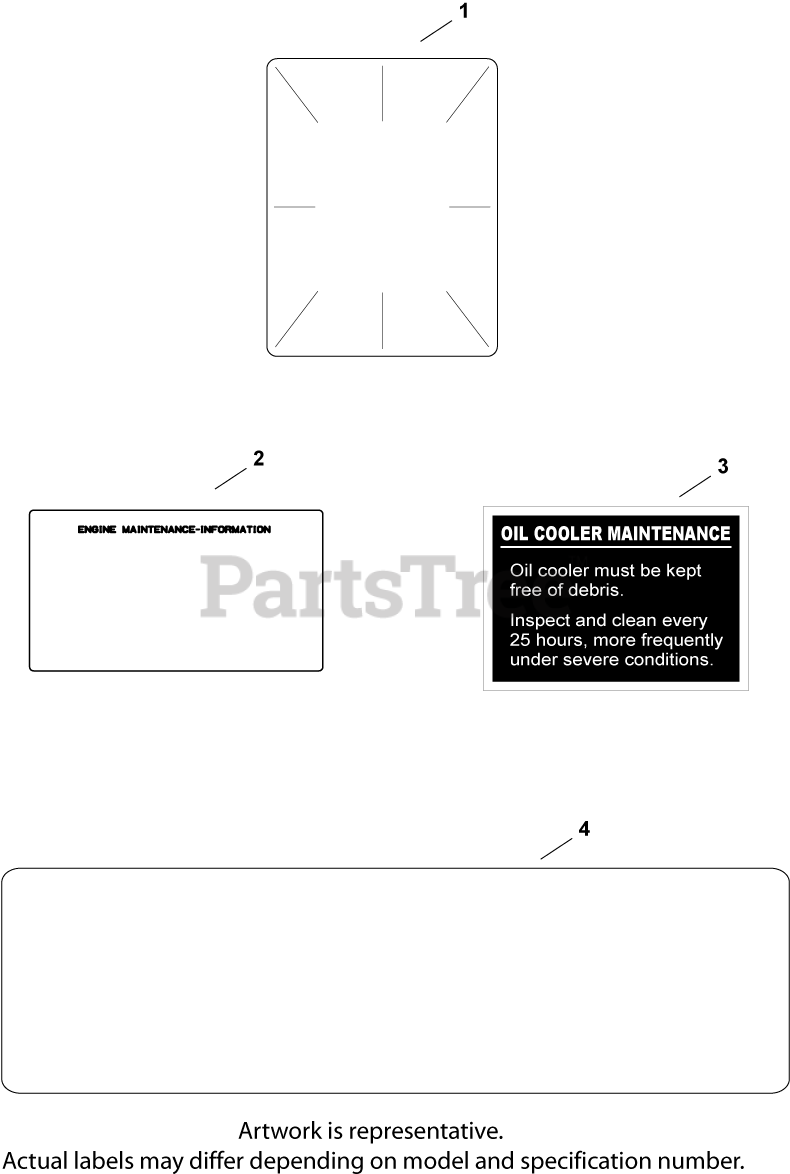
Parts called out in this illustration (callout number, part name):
1	DECAL, CLEAR LAMINATE USE 25 113 70-S
2	DECAL, ENGINE MAINT. - (#DSC)
3	DECAL, OIL COOLER - (#DSC)
4	DECAL, 22 HP
